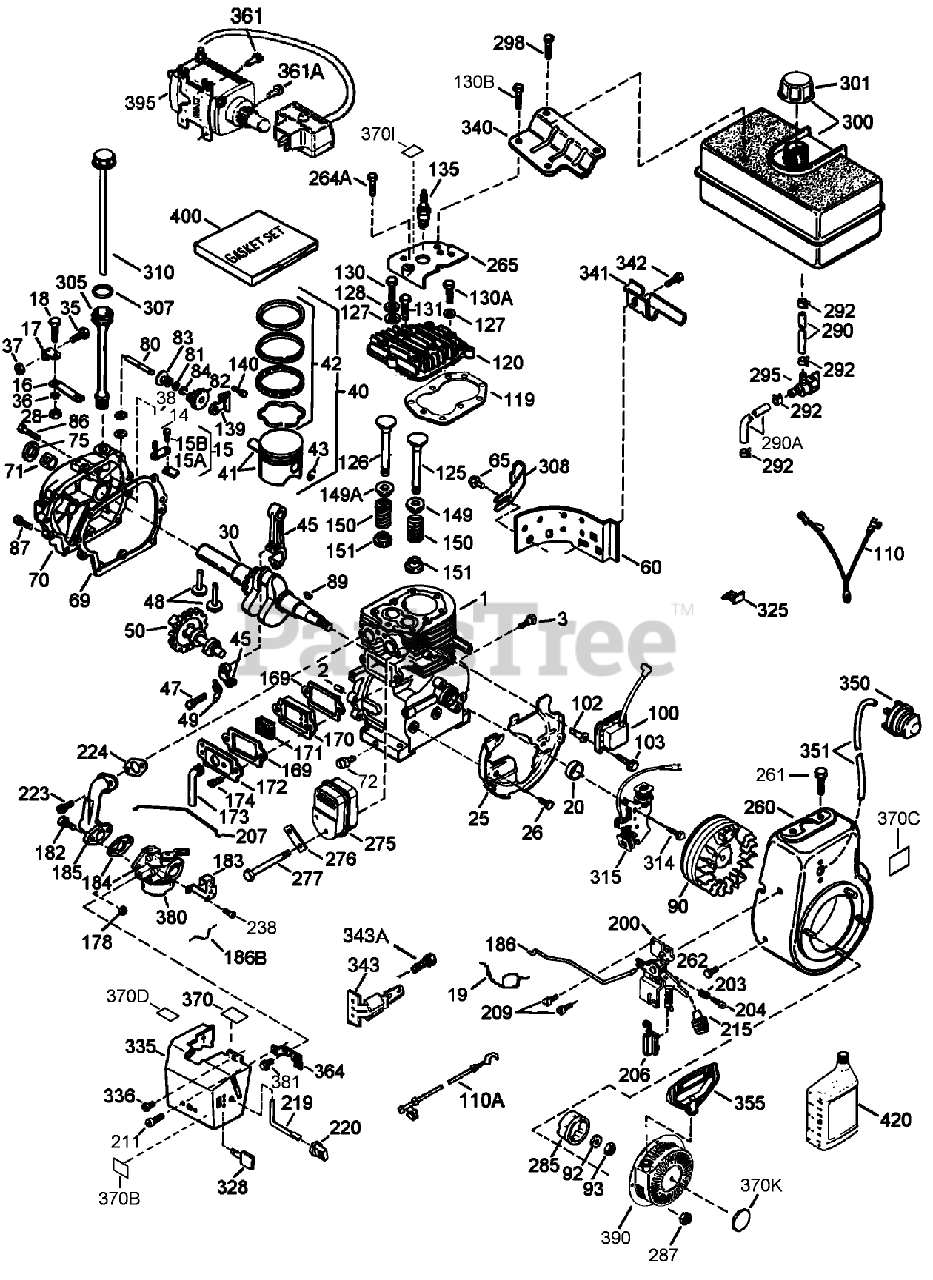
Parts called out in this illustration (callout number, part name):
203	Spring-Compression
204	Screw (T-10, 5-40x7/16)
206	Terminal
207	Link-Throttle
209	Screw (10-32 x 1/2)
211	Screw (10-32 x 3/8)
215	Knob-Control
219	Rod-Choke
220	Knob-Control
223	Screw (T-30, 5/16-18x1-3/32)
224	Gasket-Pipe, Intake
238	Screw (10-32 x 1/2)
260	Housing-Blower
261	Screw (5/16-18x3/4)
262	Screw (5/16-18x9/16)
264A	Screw (1/2-20x5/8)
265	Cover-Head, Cylinder (Black)
275	Muffler
276	62513 SNWTHWR W/284
277	Screw (5/16-18x4-3/16)
285	Cup-Starter
287	Nut and Lock Washer (1/4-28)
290	Line-Fuel (8.62)
290A	Line-Fuel
292	Clamp-Line, Fuel
295	Valve-Shut Off, Fuel
298	Screw (1/4-15x7/8)
300	Tank-Fuel (Includes 292, 301)
301	Cap-Fuel
305	Tube-Fill, Oil
307	O-Ring
308	Clip-Tube, Fill
310	Gauge Oil ASM
314	Screw (1/4-20 x 3/4)
315	Coil-Alternator, 18 Watt (Includes 323)
325	Clip-Wire
328	Key-Ignition
335	Cover-Carburetor (Black)
336	Screw (10-32x1/2)
340	Bracket-Tank, Fuel (Black)
341	Bracket-Tank, Fuel
342	Screw (1/4-20x19/32)
343	Bracket-Switch, Key
343A	Screw (8-32 x 23/64)
350	Primer ASM
351	Line-Primer
355	Handle-Starter, Mitten Grip
361	Screw (T-30, 1/4-20x15/32)
361A	Screw
364	Bracket-Cover, Carburetor
370	Decal-Lubrication
370B	Decal-Speed Control and Choke
370C	Decal-Primer, International Symbol
370D	Decal-Instruction
370I	Decal-Warning (Bilingual)
370K	Decal-Tecumseh Logo for Top of Recoil Starter
380	Carburetor (Incl. Ref.# 184)
381	Screw (8-32x27/64)
390	Starter-Rewind
395	Starter-Electric (110 Volt)
400	Gasket Set
420	Oil-Engine, S A E 5W30
